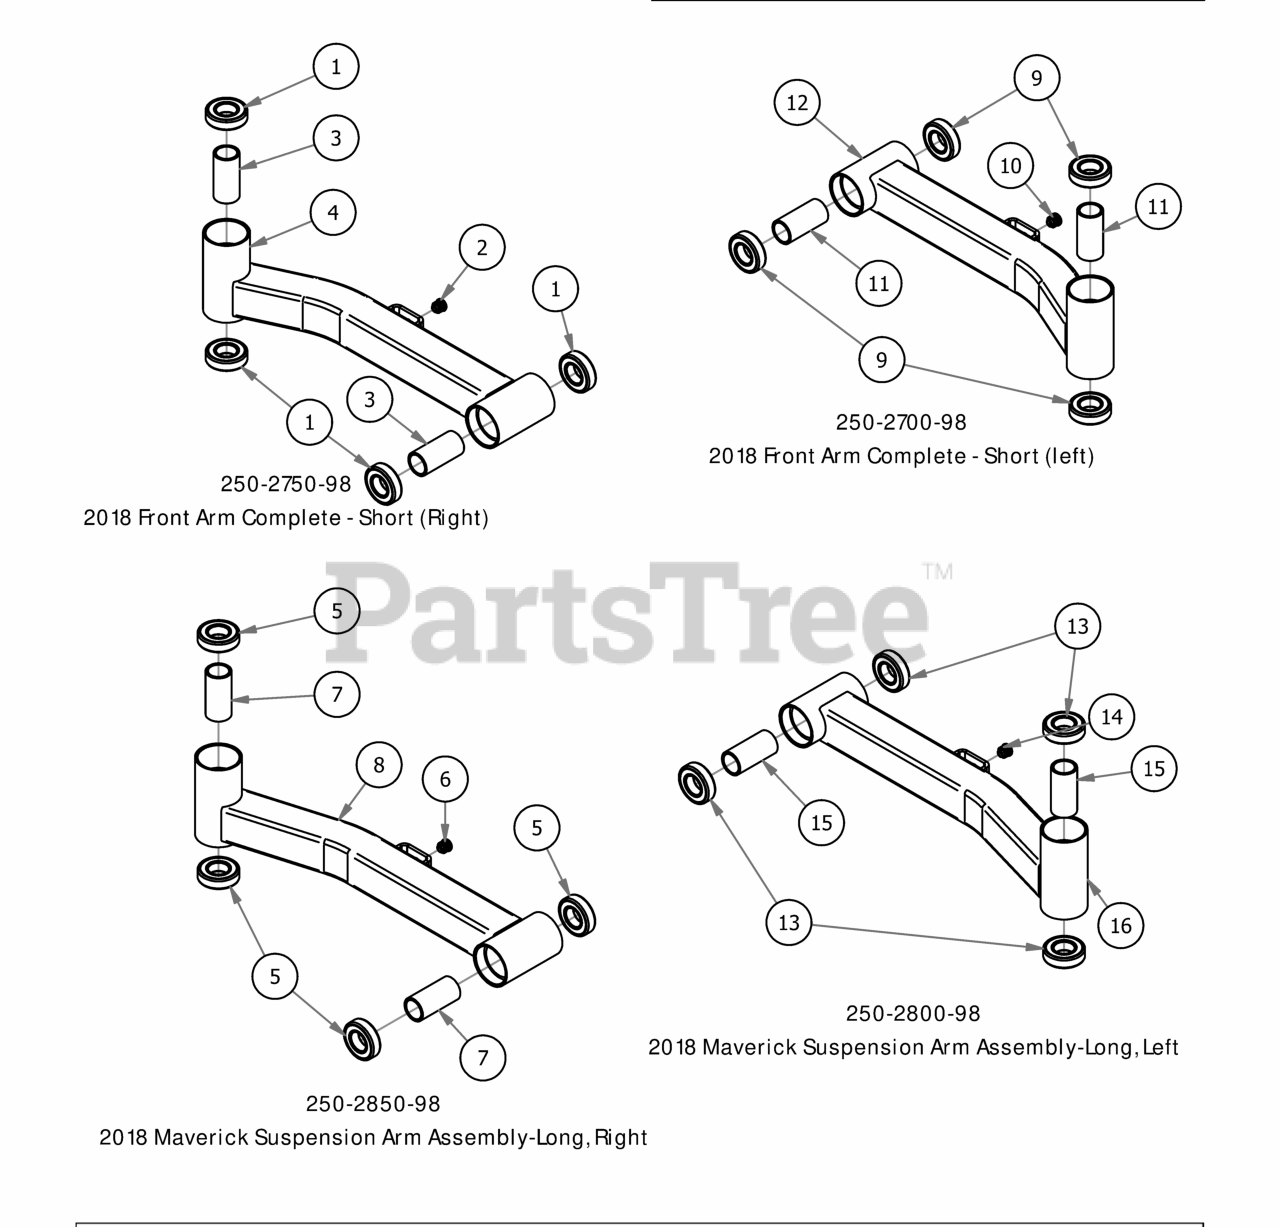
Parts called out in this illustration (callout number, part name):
1	Caster Bearing 2016 - 1641 Bearing
2	5/8 Round Insert
3	2016 Front Bearing Spacer
4	2018 Front Arm - Short (right)
5	Caster Bearing 2016 - 1641 Bearing
6	5/8 Round Insert
7	2016 Front Bearing Spacer
8	2018 Maverick Suspension Arm-Long, Right
9	Caster Bearing 2016 - 1641 Bearing
10	5/8 Round Insert
11	2016 Front Bearing Spacer
12	2018 Front Arm - Short (left)
13	Caster Bearing 2016 - 1641 Bearing
14	5/8 Round Insert
15	2016 Front Bearing Spacer
16	2018 Maverick Suspension Arm Long-Left
